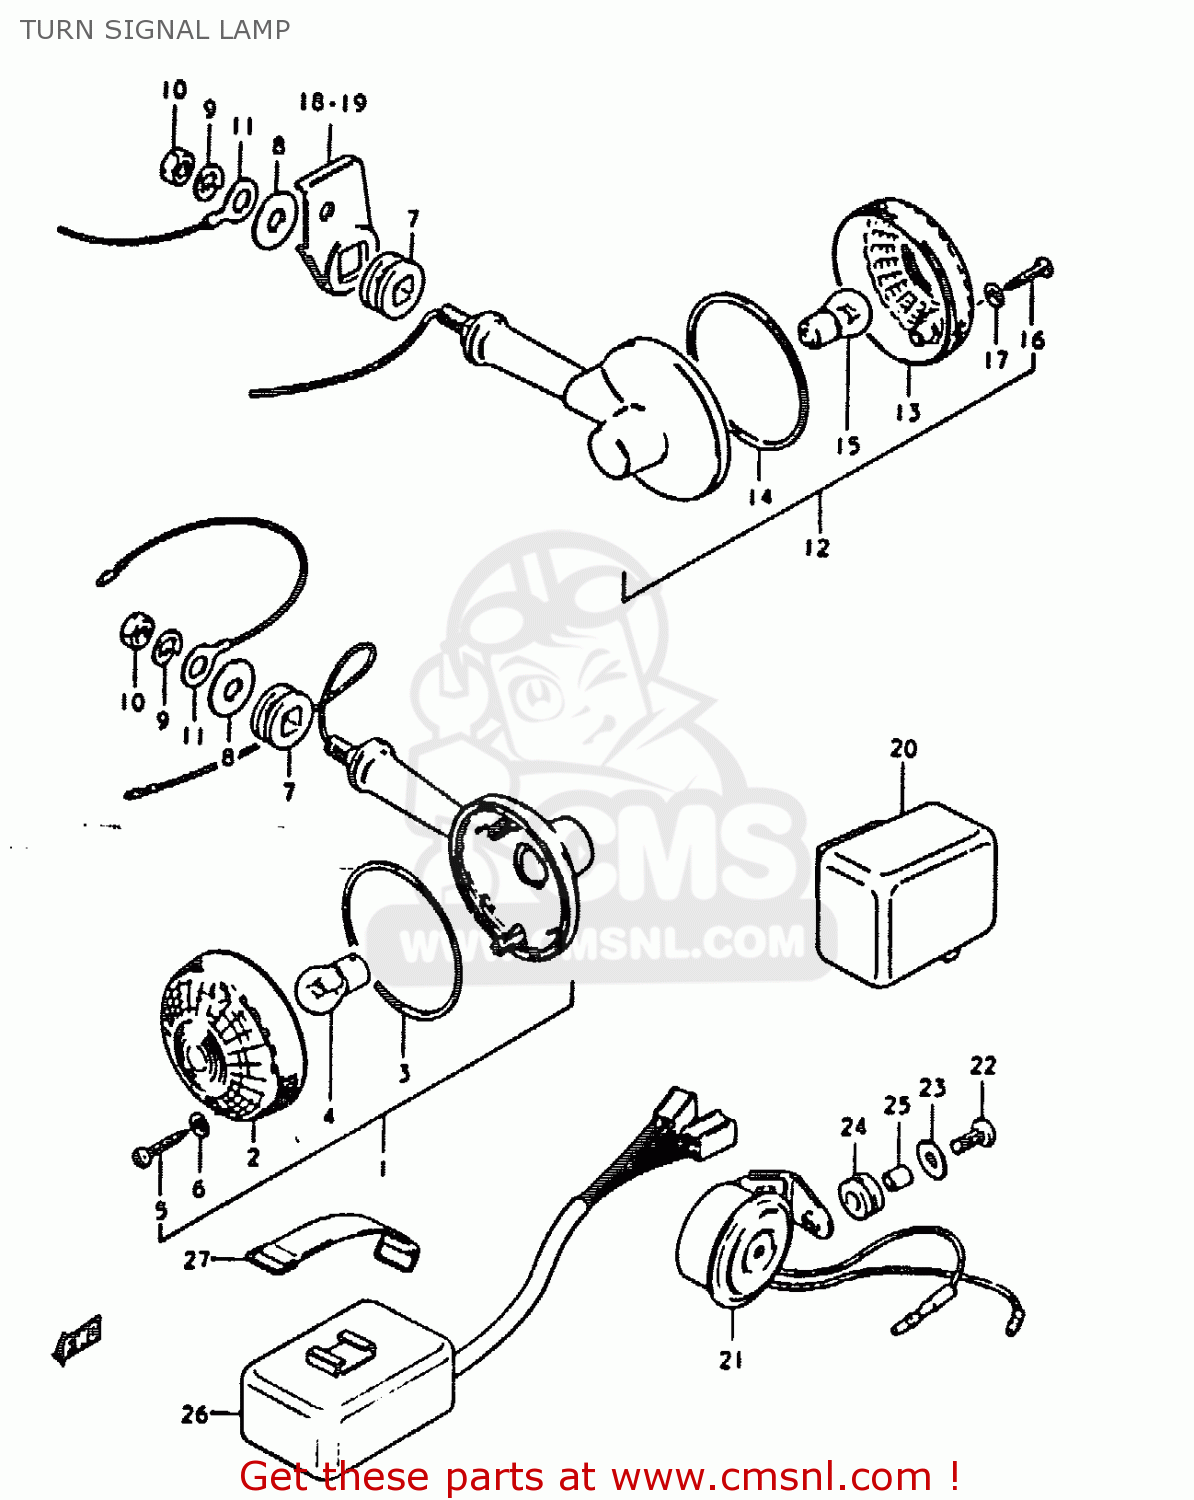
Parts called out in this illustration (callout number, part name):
1	LAMP ASSEMBLY,FRONT TURN SIGNAL
2	LENS
3	GASKET (NAS)
4	BULB(12V23W,STANLEY,A4577A)
5	BOLT
6	GASKET (NAS)
7	CUSHION
8	WASHER
9	LOCK WASHER
10	NUT
11	LEAD WIRE,EARTH
12	LAMP ASSEMBLY,FRONT TURN SIGNAL
13	LENS
14	GASKET (NAS)
15	BULB(12V23W,STANLEY,A4577A)
16	BOLT
17	GASKET (NAS)
18	BRACKET,RR TURNSIGNAL LAMP,R
19	BRACKET,RR TURNSIGNAL LAMP,L
20	RELAY,TURN SIGNAL
21	BUZZER ASSEMBLY,TURN SIGNAL
22	SCREW
23	WASHER
25	WASHER(6X13X2)
